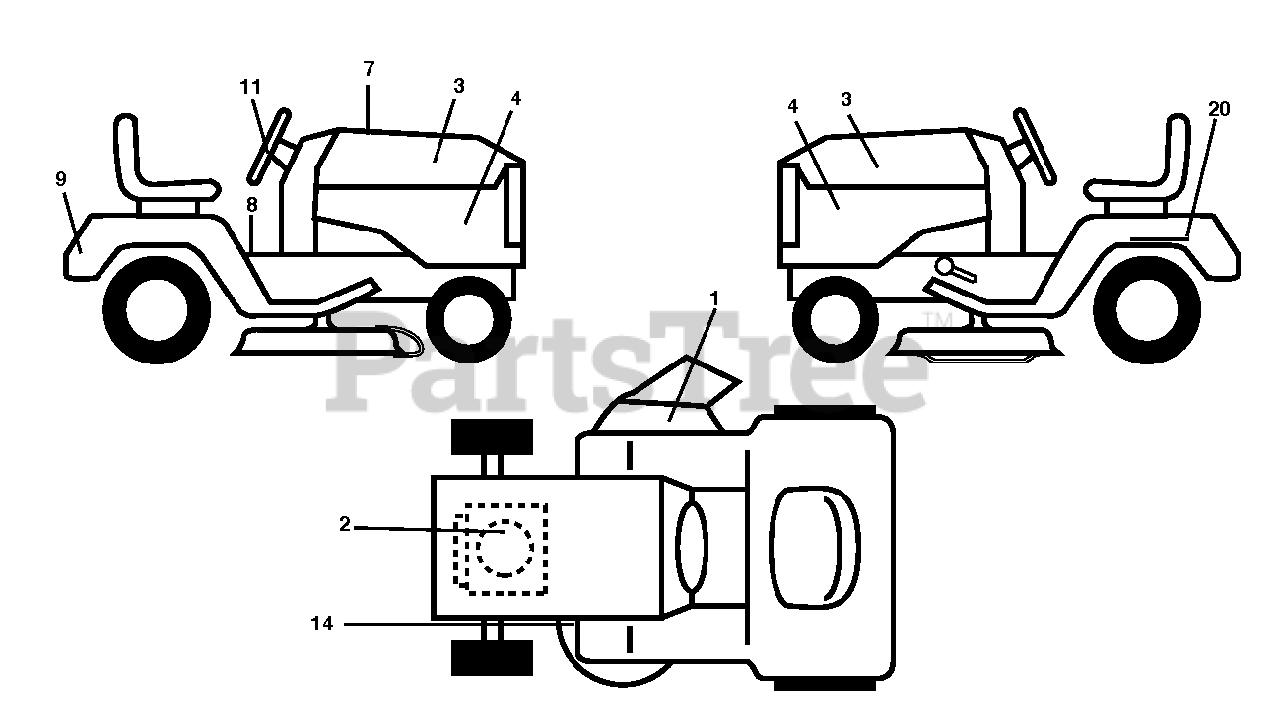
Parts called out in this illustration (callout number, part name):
1	DECAL, DECK DEFLECTOR, WARNING
2	Decal, Engine BS 18 5INTK 381713
3	DECAL.POULAN PRO.2015
4	DECAL TRACTOR SIDE PANEL DECAL
7	DECAL DECAL.RPL.BSM33.INTK.TLW
8	DECAL.WARNING.2007.ENG/FR
9	DECAL.REARFNDR.POULAN PRO.2015
11	Decal, Steering Wheel STDXXSQ PPRO 2015
14	DECAL.V-BELT.SCH.42/46"MEC/ELE
20	DECAL BTRY SYMBOLS
